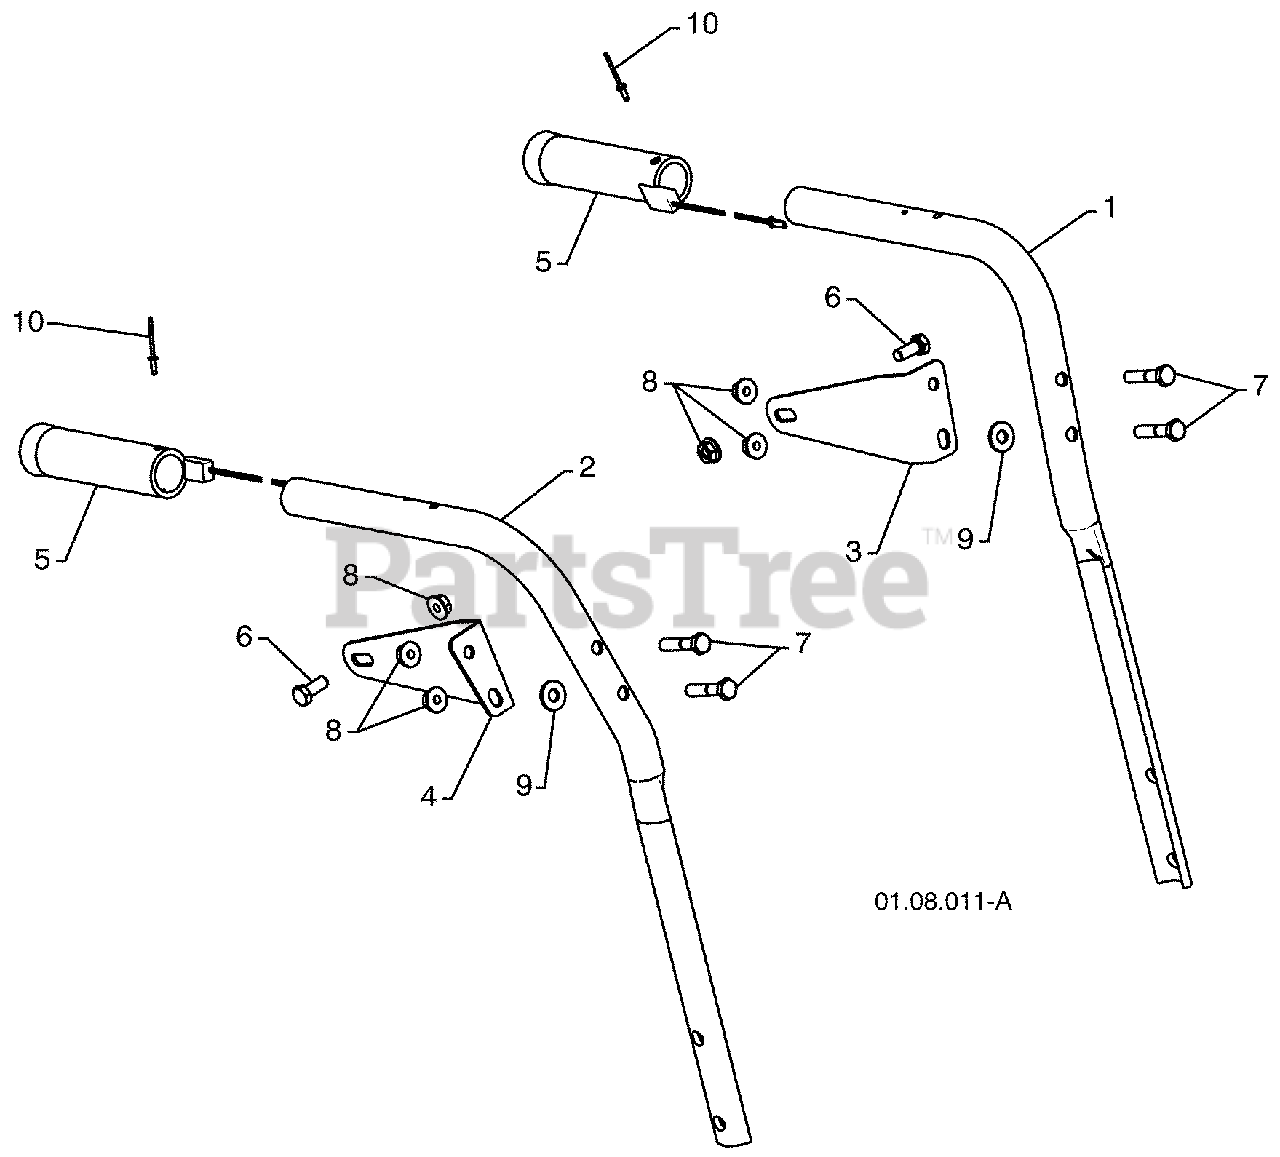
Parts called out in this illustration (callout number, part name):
1	PLOW HANDLE LH
2	PLOW HANDLE RH
3	PANEL BRACKET LH
4	PANEL BRACKET RH
5	HEATED HANDLE GRIP
6	SCREW 5/16-18 X .750
7	SCREW 5/16-18 X 1.50
8	NUT 5/16-18
10	POP RIVET 1/8
